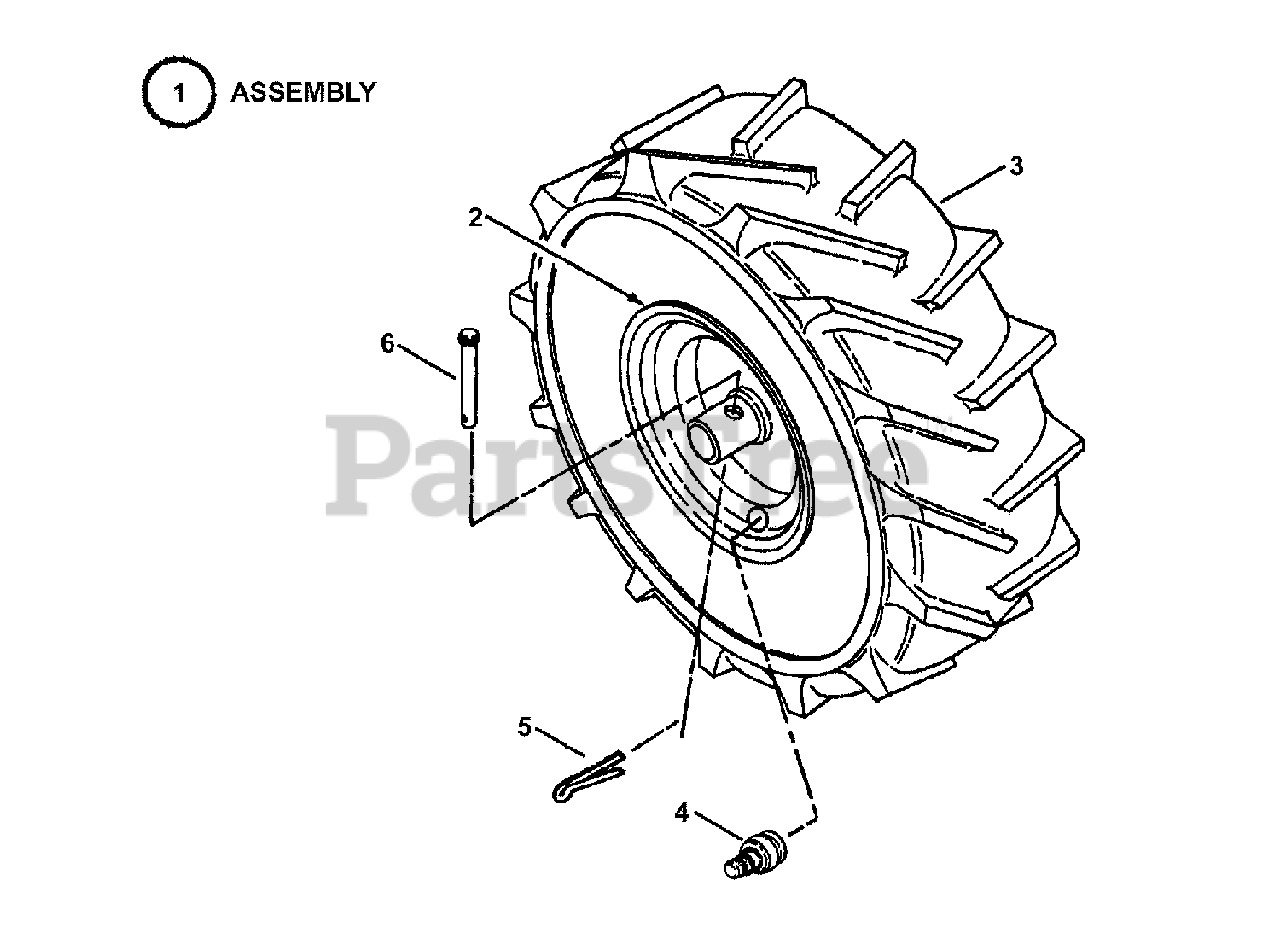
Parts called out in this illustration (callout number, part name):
1	ASSEMBLY, Right Wheel (Incl. items 2, 3 & 4)
3	TIRE, 13 x 5.00 x 6 (Lug)
4	VALVE, Air (Snap-In)
5	PIN, 5/16" Self-Locking Cotter
6	PIN, 5/16 x 1-11/16" Clevis
